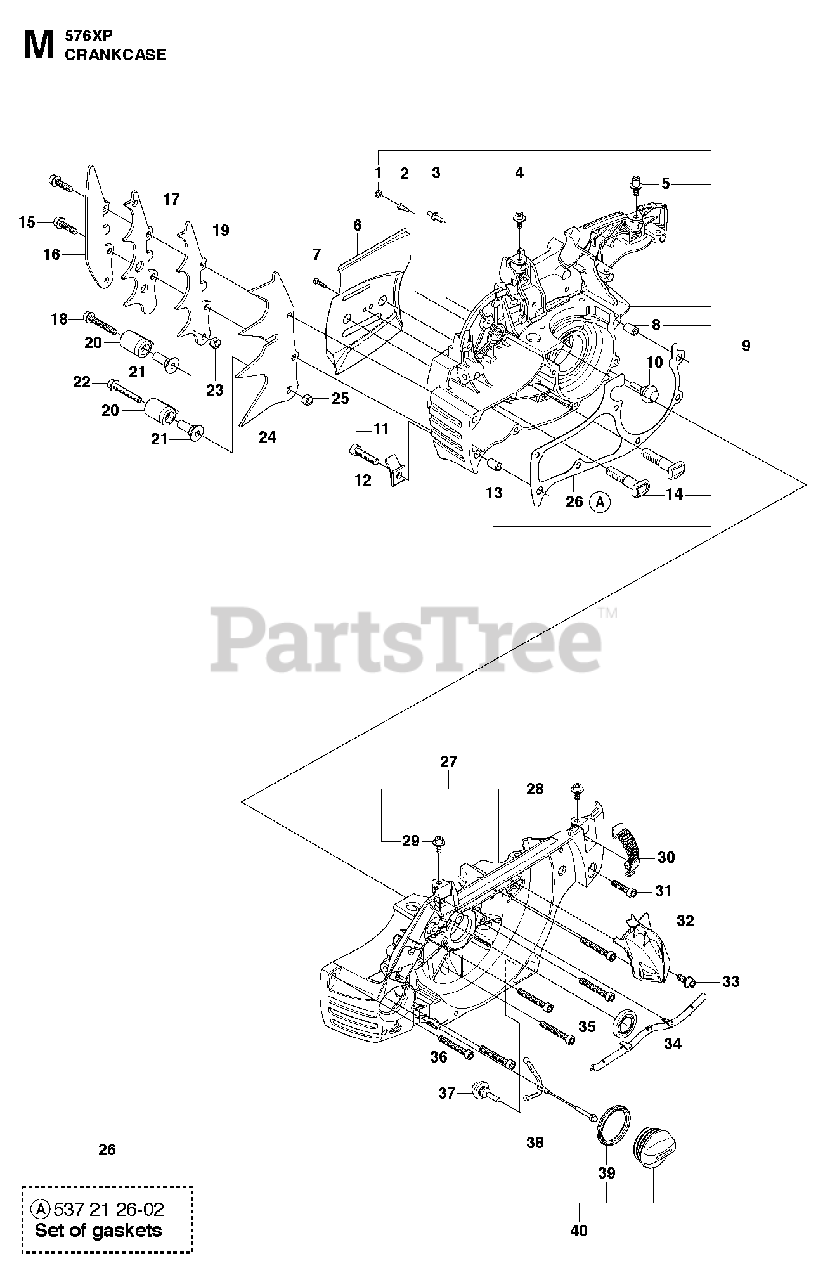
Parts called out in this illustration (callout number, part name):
1	PLUG
2	VALVE-CHECK (DUCKBILL)
3	PIN
4	SCREW IHSCM
5	SCREW IHSCM
8	SLEEVE
9	CRANKCASE ASSY
12	CHAIN CATCHER
13	SLEEVE
14	BOLT
17	FELLING DOG
18	SCREW
19	FELLING DOG
21	CHAIN CATCHER
22	SCREW
24	FELLING DOG
26	GASKET KIT
27	CRANKCASE ASSY
28	SCREW IHSCM
29	SCREW IHSCM
30	BUCKLE ORANGE
30	CLIP GRAY
33	SCREW
35	RADIAL SEAL
38	TANK LOCK
39	SEALING
40	TANK CAP
